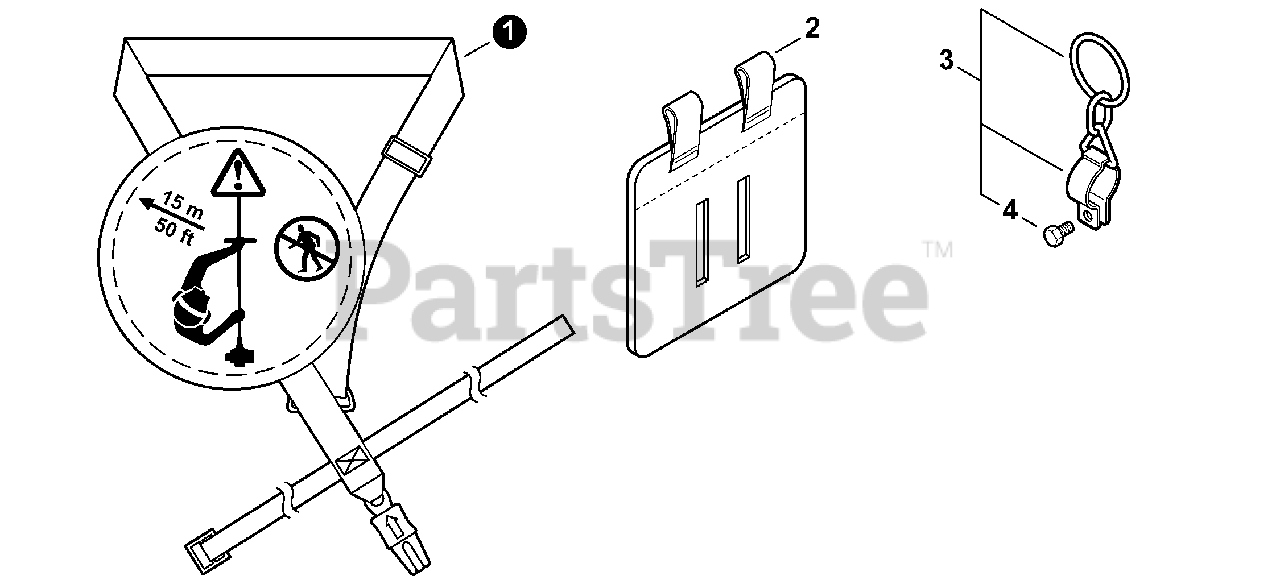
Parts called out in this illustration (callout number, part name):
1	HARNESS, SHOULDER
2	PAD, HIP
3	HANGER SET, HARNESS
4	BOLT 5×12
